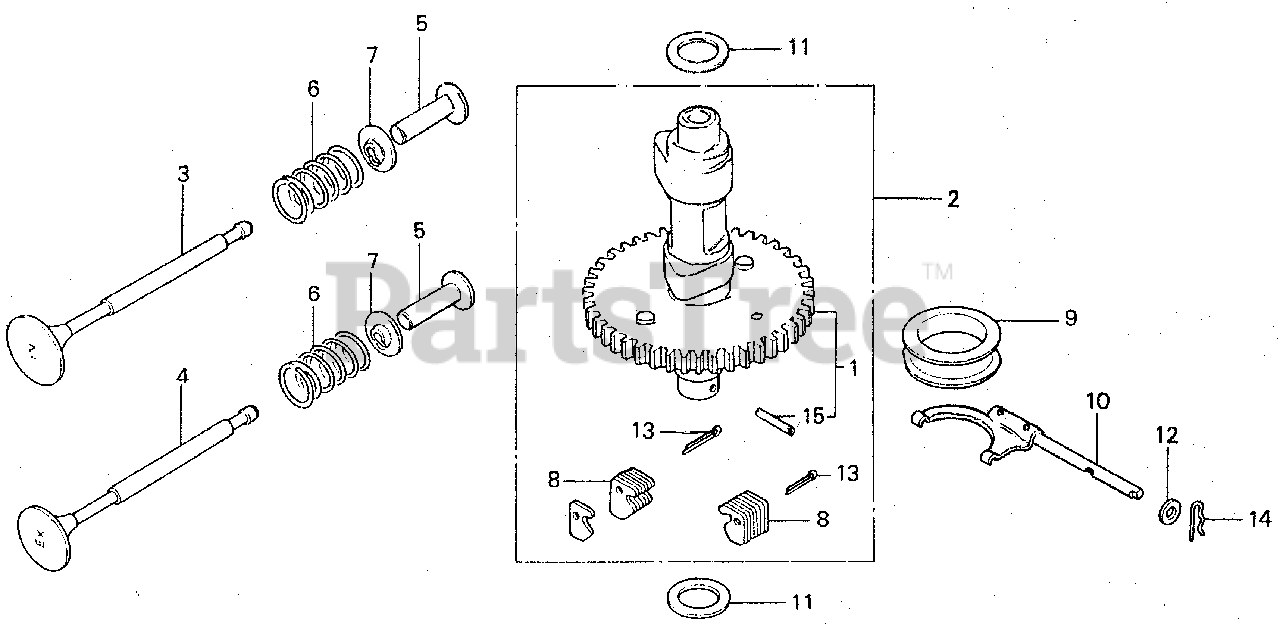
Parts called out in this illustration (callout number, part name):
2	CAMSHAFT ASSY.
3	VALVE, IN.
4	VALVE, EX.
5	LIFTER, VALVE (39.6MM)
5	LIFTER, VALVE (39.9MM)
6	SPRING, VALVE
7	RETAINER, VALVE SPRING
8	WEIGHT, GOVERNOR
9	SLIDER, GOVERNOR
10	SHAFT, GOVERNOR (NOT AVAILABLE)
11	WASHER, THRUST (18MM)
12	WASHER, PLAIN (6MM)
13	PIN, SPLIT (3.0X25)
13	PIN, SPLIT (3.0X45)
14	PIN, LOCK (8MM)
15	PIN, SPRING (2.5X16)
